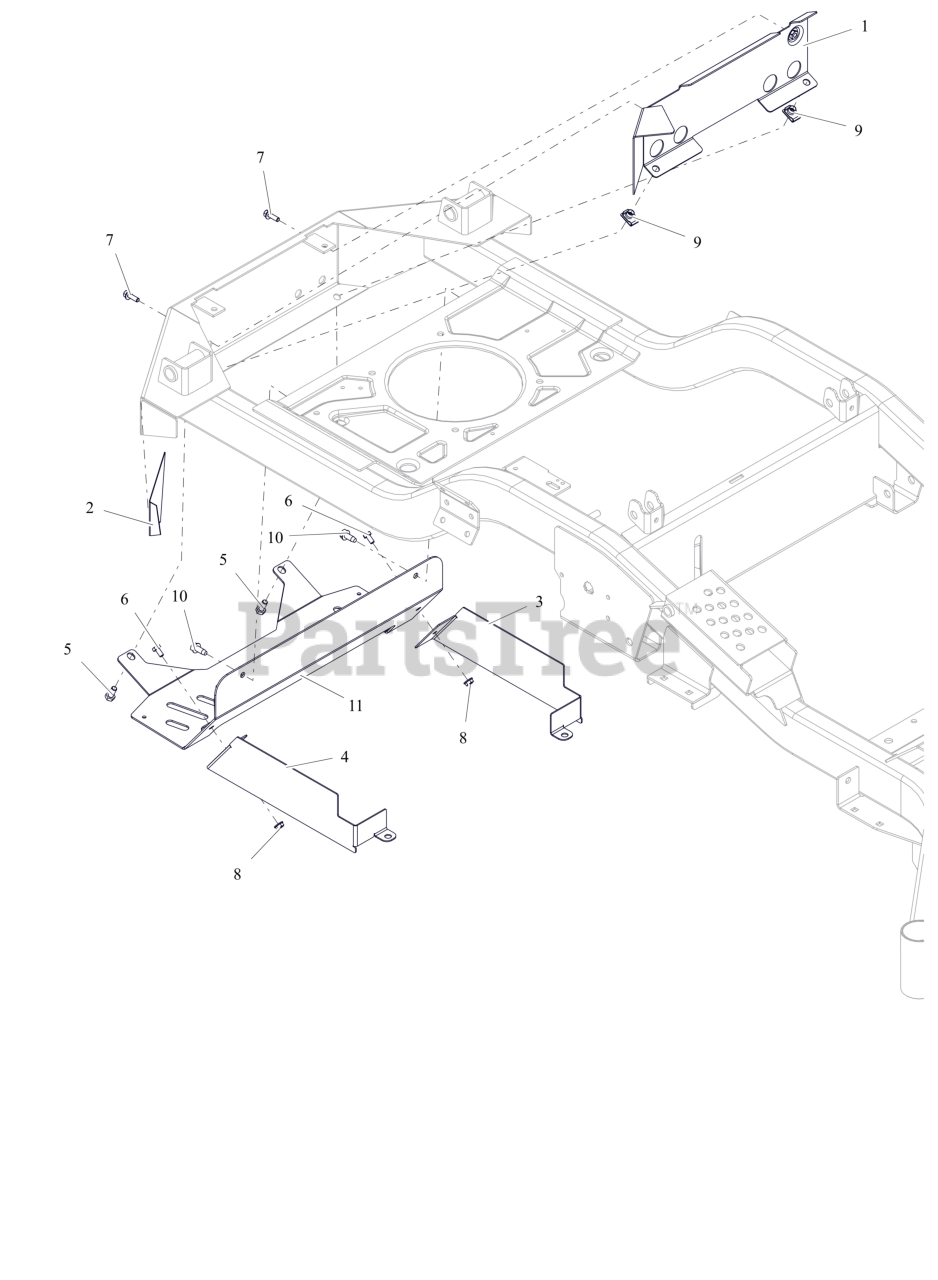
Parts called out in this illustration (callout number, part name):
1	WMT, HEAT BAFFLE
2	TAPE, HEAT DEFLECTOR
3	GUARD,REAR CLUTCH LH
4	GUARD,REAR CLUTCH RH
5	BLT,HEX .31-18X.75 G5 ZCC
6	BLT,HEX .25-20X.50 G5 ZCC
7	BLT,HEX-FLG .25-20X.75 G5 BFP
8	NUT-LK-TOP-FLG .250-20 GF ZCC
9	NUT-CLIP RETAINER 5/16-18X.56
10	SCR,TAP .312-18X.75 HWH TR ZCC
11	SHIELD, HEAT (HD) (BLACK)
